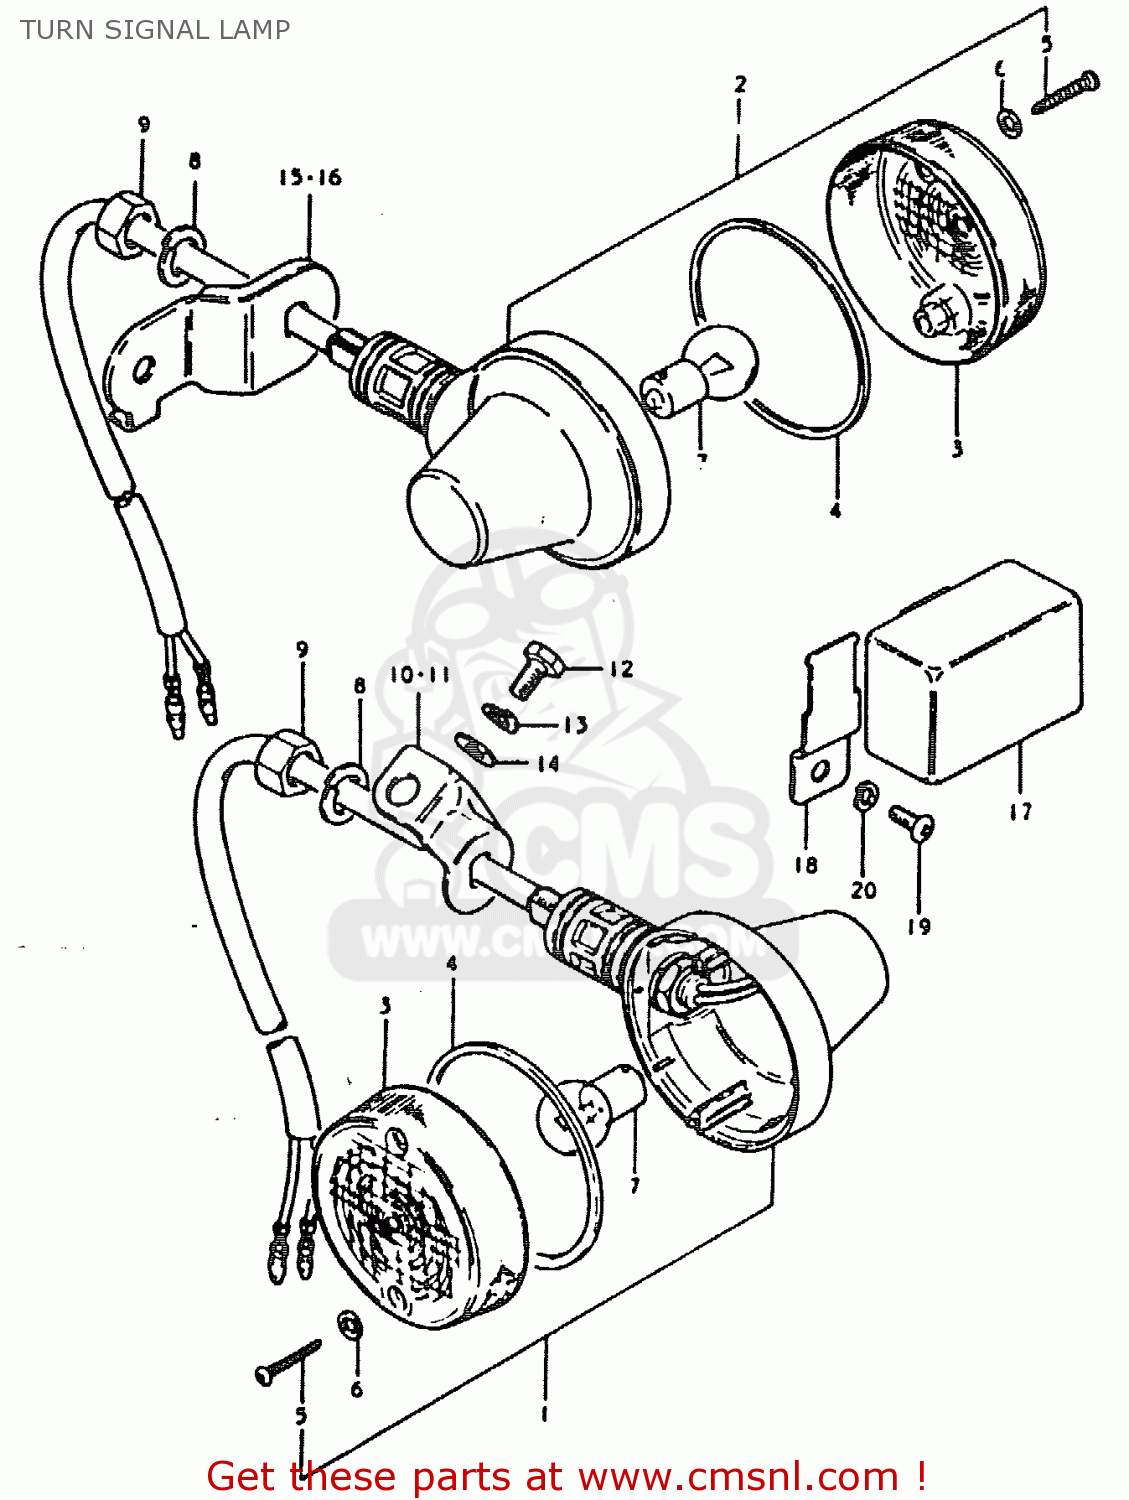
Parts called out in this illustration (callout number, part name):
1	LAMP ASSY,RR TURNSIGNAL
2	LAMP ASSY,RR TURNSIGNAL
3	LENS
4	GASKET (NAS)
5	SCREW TAPP.
6	GASKET (NAS)
7	BULB(6V17W,STANLEY,A4513A)
8	WASHER,LOCK 12
9	NUT
10	BRACKET,TURN SIGNAL LAMP
11	BRACKET,TURN SIGNAL LAMP
12	BOLT
13	LOCK WASHER
14	WASHER
15	BRACKET,REAR TURN SIGNAL
16	BRACKET,REAR TURN SIGNAL
17	RELAY,TURN SIGNAL
18	BRACKET,TURN SIGNAL RELAY
19	SCREW 6X12
20	LOCK WASHER
